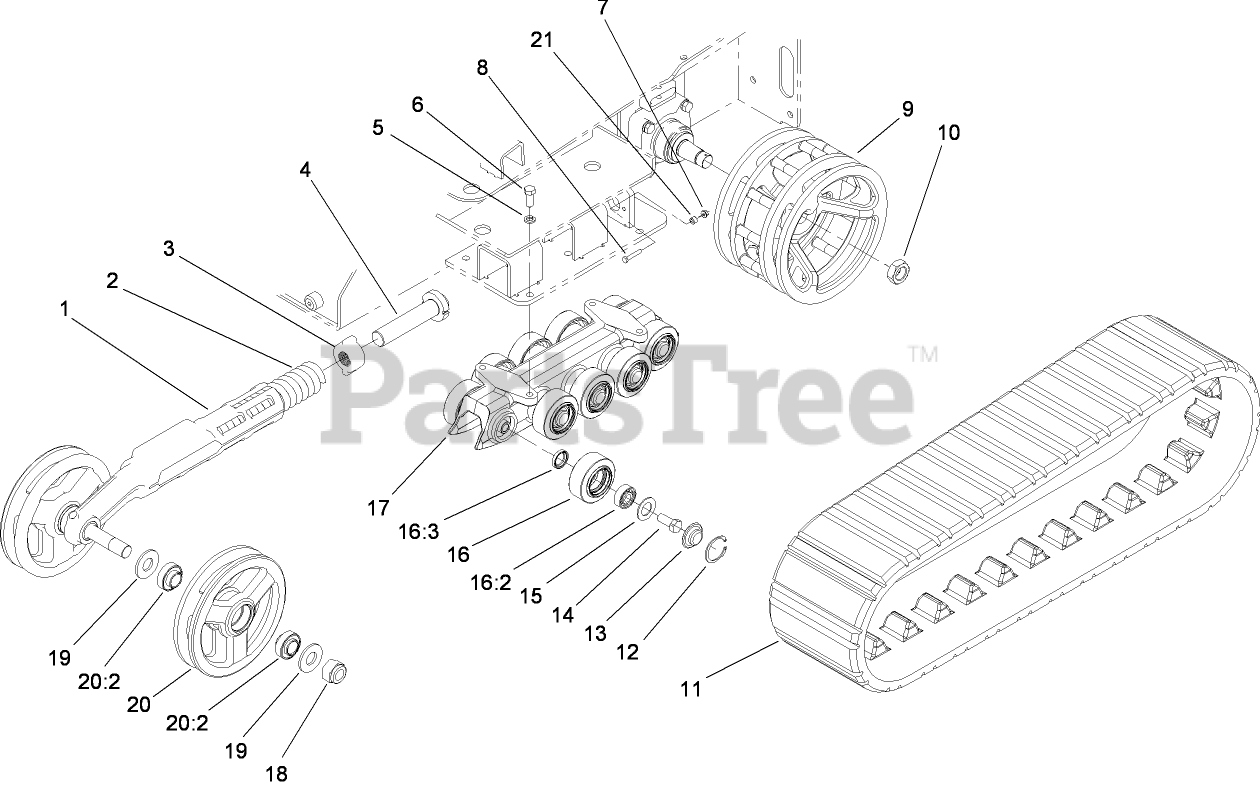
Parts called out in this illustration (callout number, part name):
1	ARM-TENSIONER
2	SPRING-COMPRESSION
3	BLOCK-TENSIONER
4	BOLT-TENSIONER
5	WASHER-LOCK
6	SCREW-HH
7	NUT-HHF
8	SCREW-HH
9	WHEEL-DRIVE
10	NUT-HEX
11	TRACK
12	RING-SNAP, INTERNAL
13	CAP-WHEEL, BEARING
14	SCREW-HH
15	Gasket-Bogie
16	Road Wheel ASM
16:2	BEARING
16:3	SEAL-OIL
17	GUIDE-TRACK
18	NUT-HEX, NI
19	WASHER-PLAIN
20	Tensioner Wheel ASM
20:2	Bearing-Ball
21	SPACER
